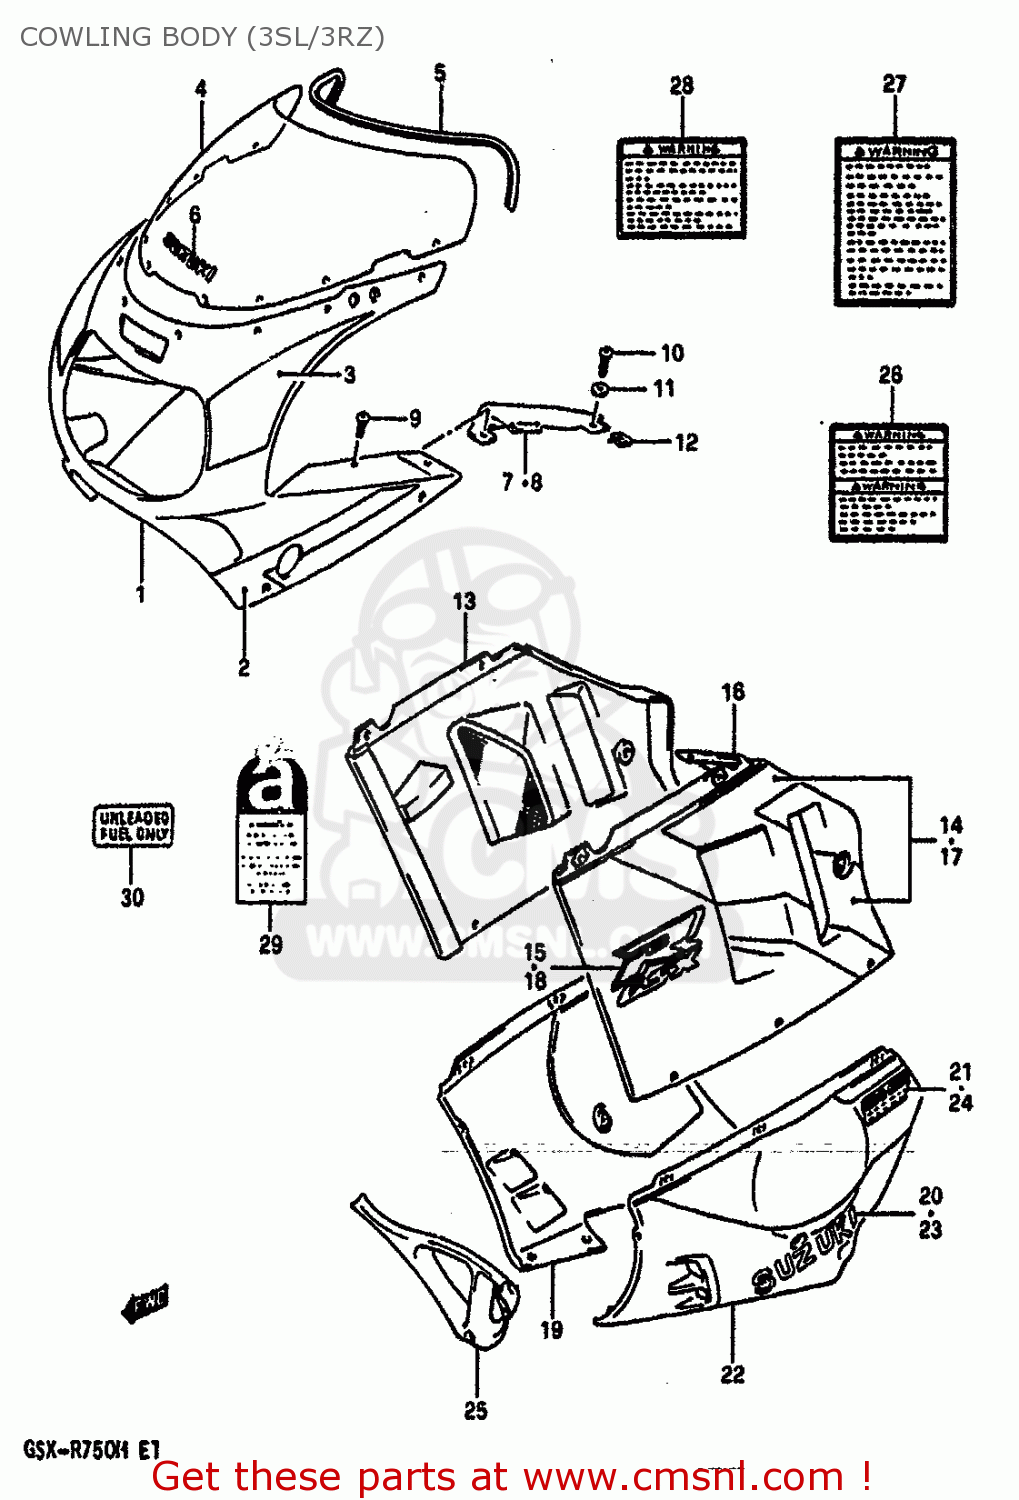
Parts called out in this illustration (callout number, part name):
1	BODY ASSY,COWLING
2	TAPE SET,SIDE
3	TAPE SET,FRONT
4	SCREEN SET,WIND
5	MOLDING
6	EMBLEM,SUZUKI(WHITE)
7	PANEL,COWLING UPR,R
8	PANEL,COWLING,UPPER,LEFT
9	SCREW(5X10)
10	SCREW(5X14)
11	WASHER(5.2X11X1)
12	NUT
13	COVER,COWLING SIDE RH (WHITE/RED)
14	TAPE SET,SIDE RH
15	EMBLEM,COWLING SIDE
16	COVER,COWLING SIDE LH (WHITE/RED)
17	TAPE SET,SIDE LH
18	EMBLEM,COWLING SIDE
19	COWLING,UNDER RH (WHITE/RED)
20	EMBLEM
21	EMBELEM,SACS
22	COWLING,UNDER
23	EMBLEM
24	EMBELEM,SACS
25	COWLING,UNDER,CENTER (W
26	LABEL (WARNING)
27	LABEL (WARNING SCREEN)
28	LABEL, WARNING SAFETY
29	LABEL,ASBESTOS WARNING
30	LABEL,FUEL CAUTION
